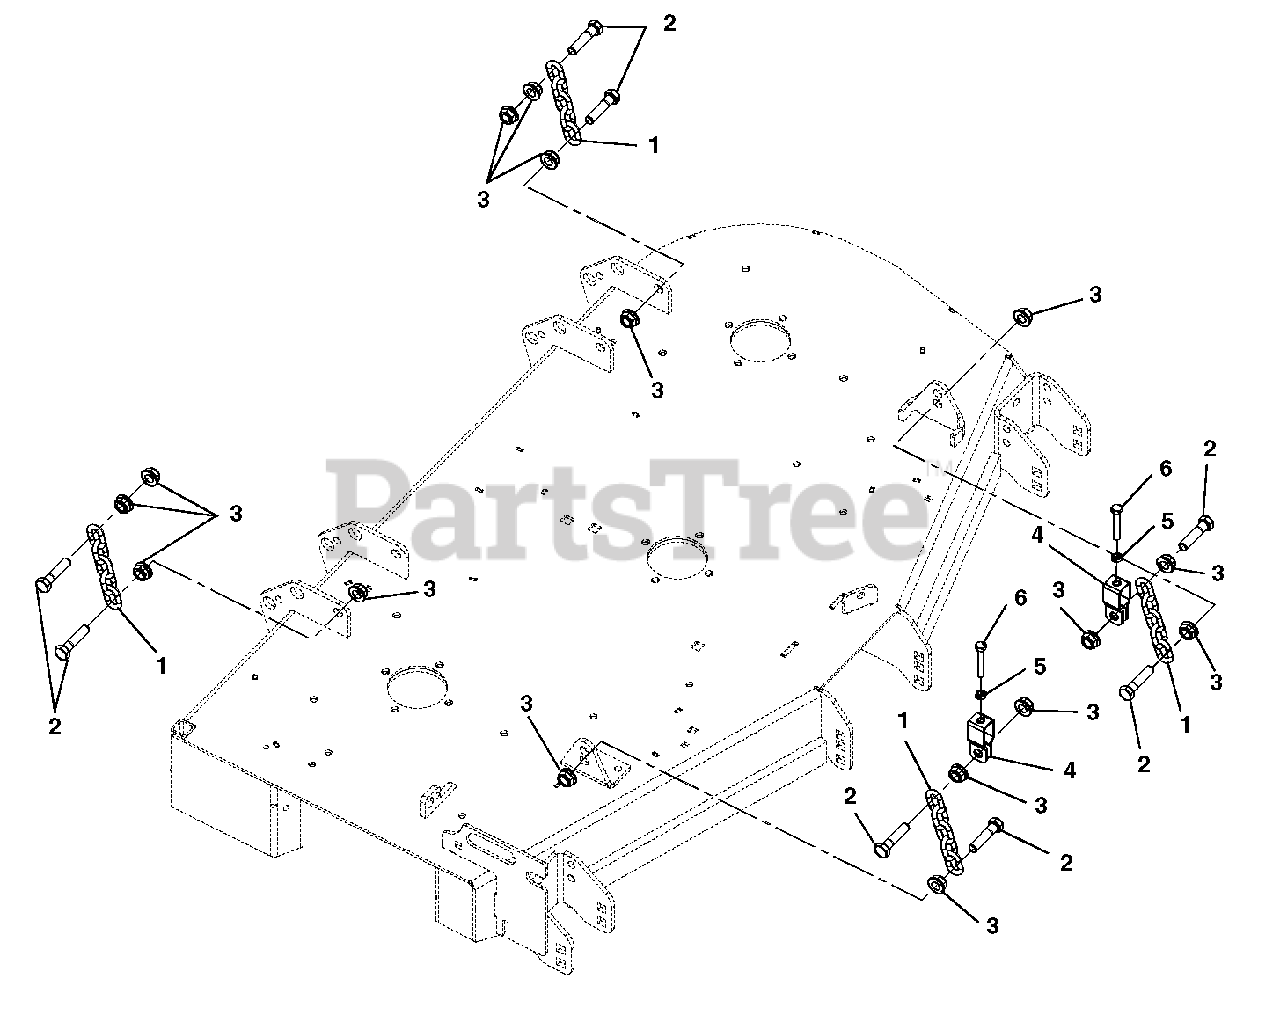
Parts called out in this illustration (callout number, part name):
1	Chain, Link
2	Bolt, Hex M12-1.75 x 50 Class 8.8
3	Nut, Spin Lock-Flange M12-1.75
4	Bracket, Deck Leveling
5	Nut, Jam .312-18
6	Bolt, Hex .312-18 x 2.00 Full Thread Grade 5
